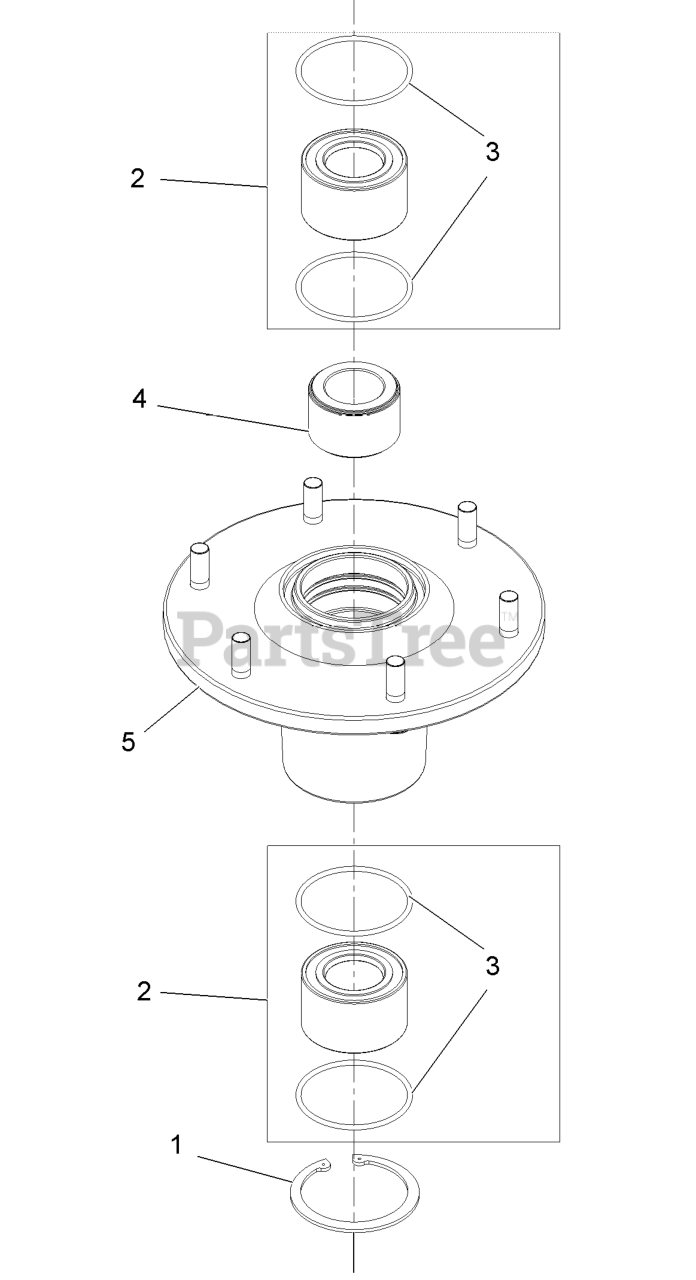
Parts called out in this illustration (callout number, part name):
1	RING-RETAINING
2	ASM, BEARING W/ORINGS
4	SPACER,BEARING
5	ASM,HOUSING W/STUDS
